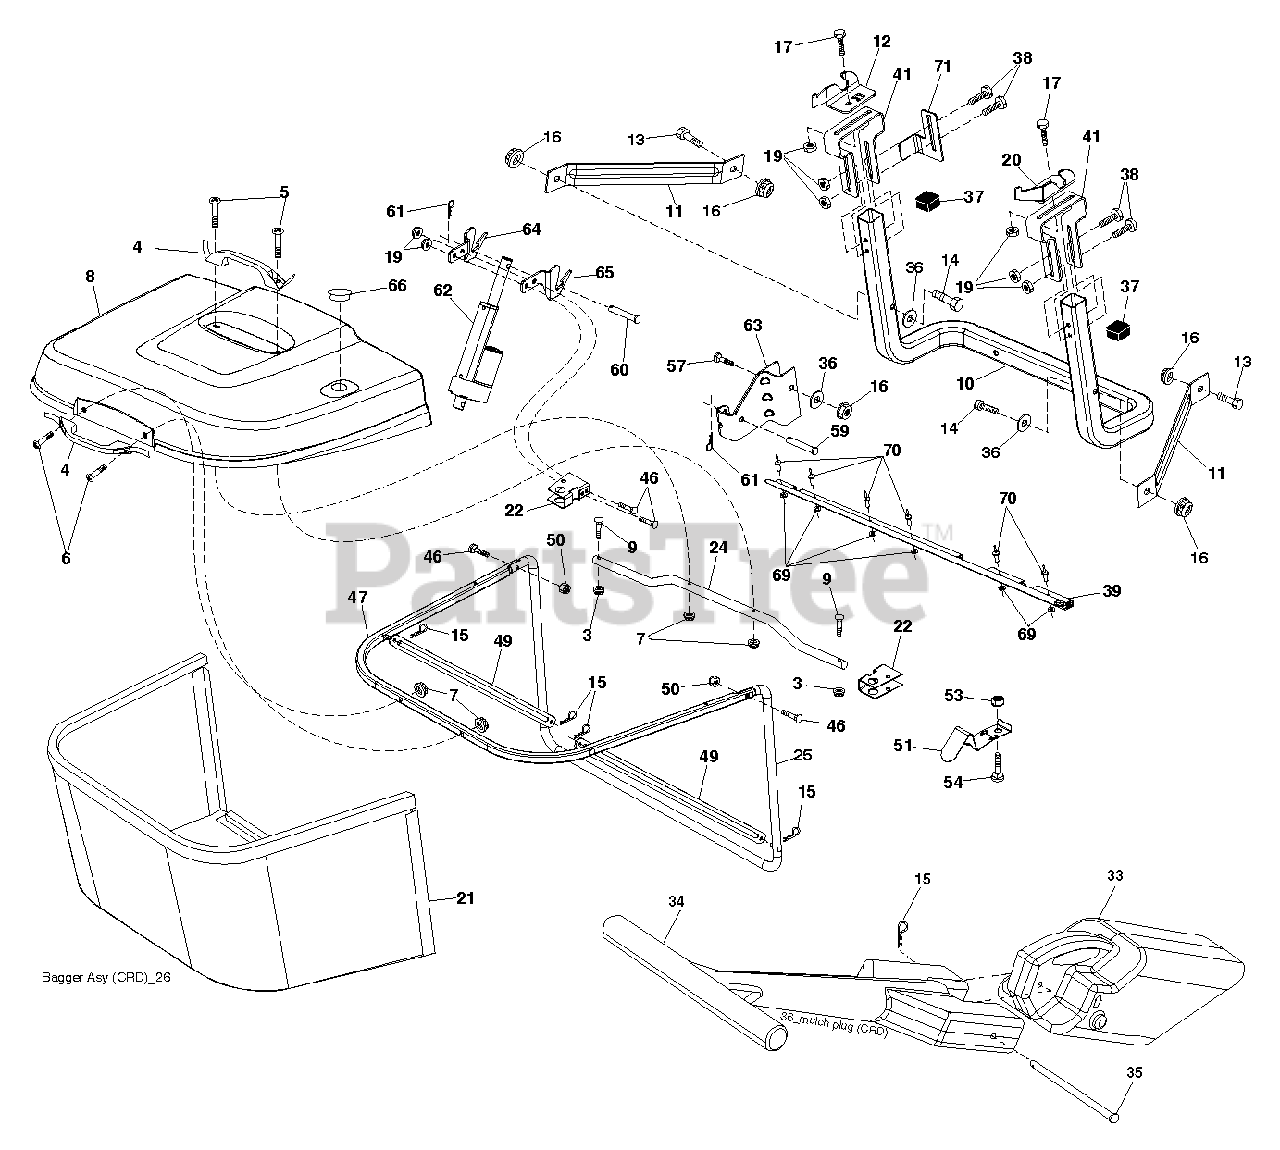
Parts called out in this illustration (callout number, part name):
3	NUT T
5	SCREW.PAN.HEAD
11	BRACKET
14	BOLT-HEX EAK
15	RETAINER-SPRNG RB
16	NUT LOCK FLG 3/8-16 UNC
17	BOLT
19	NUT LOCK HEX FLANGE 5/16-18
20	BRKT.PIVOT.RH.CRD
21	BAGGER.ASM.CRD.2007
22	BRACKET.BAGGER.SD.
24	TUBE
33	MULCHING.PLUG.1078.CRD.NON-TEX
35	PIN
38	BOLT.5/16-18X2.5
39	SEAL.BAGGER.CRD
41	BRACKET.BAGGER.SD.
46	BOLT.CARRIAGE.5/16-18
50	NUT.71038.31-18.HEX.NYLOCK
53	NUT
54	BOLT
61	RETAINER M
